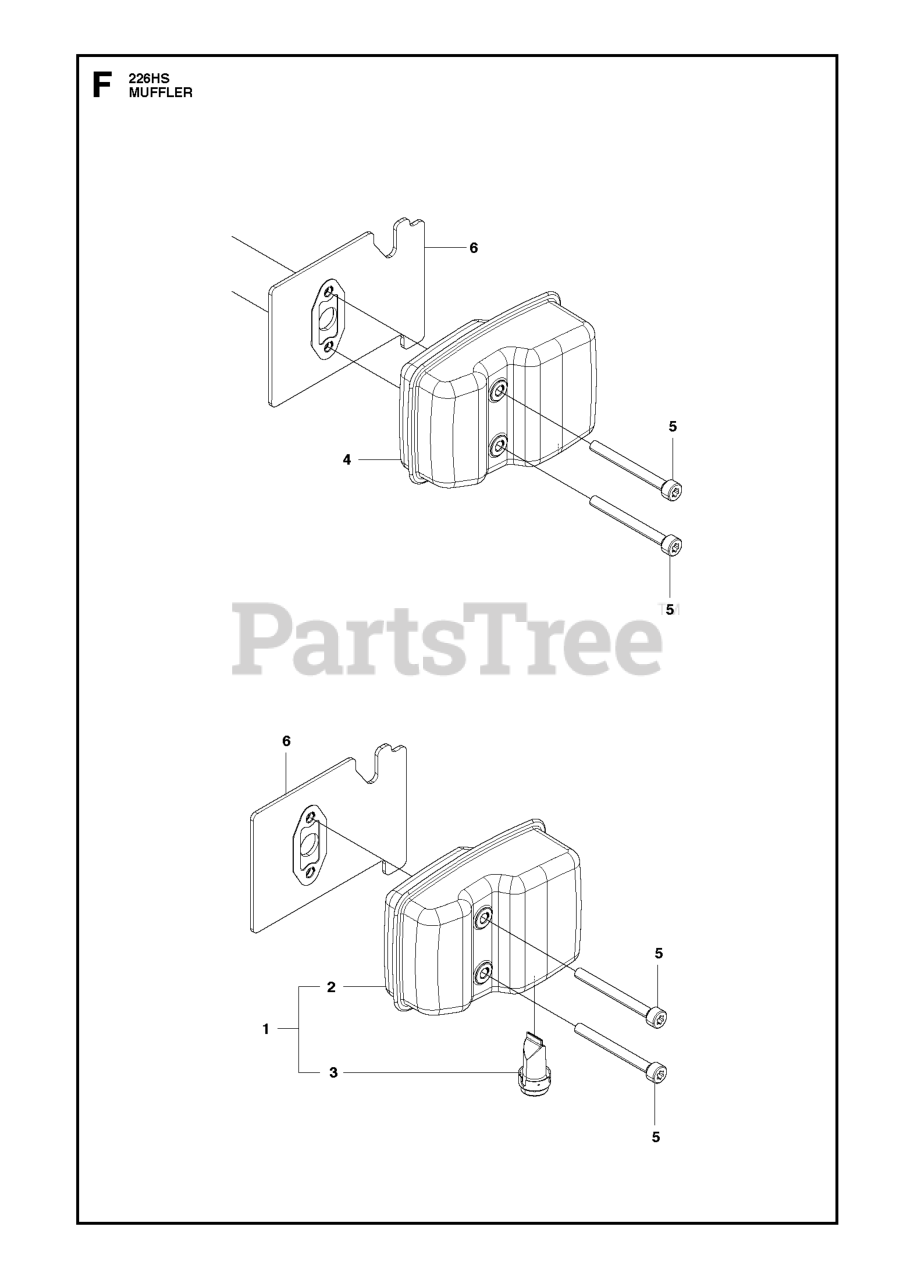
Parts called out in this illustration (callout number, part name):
1	MUFFLER
2	RP MUFFLER
3	ARRESTER
4	MUFFLER
